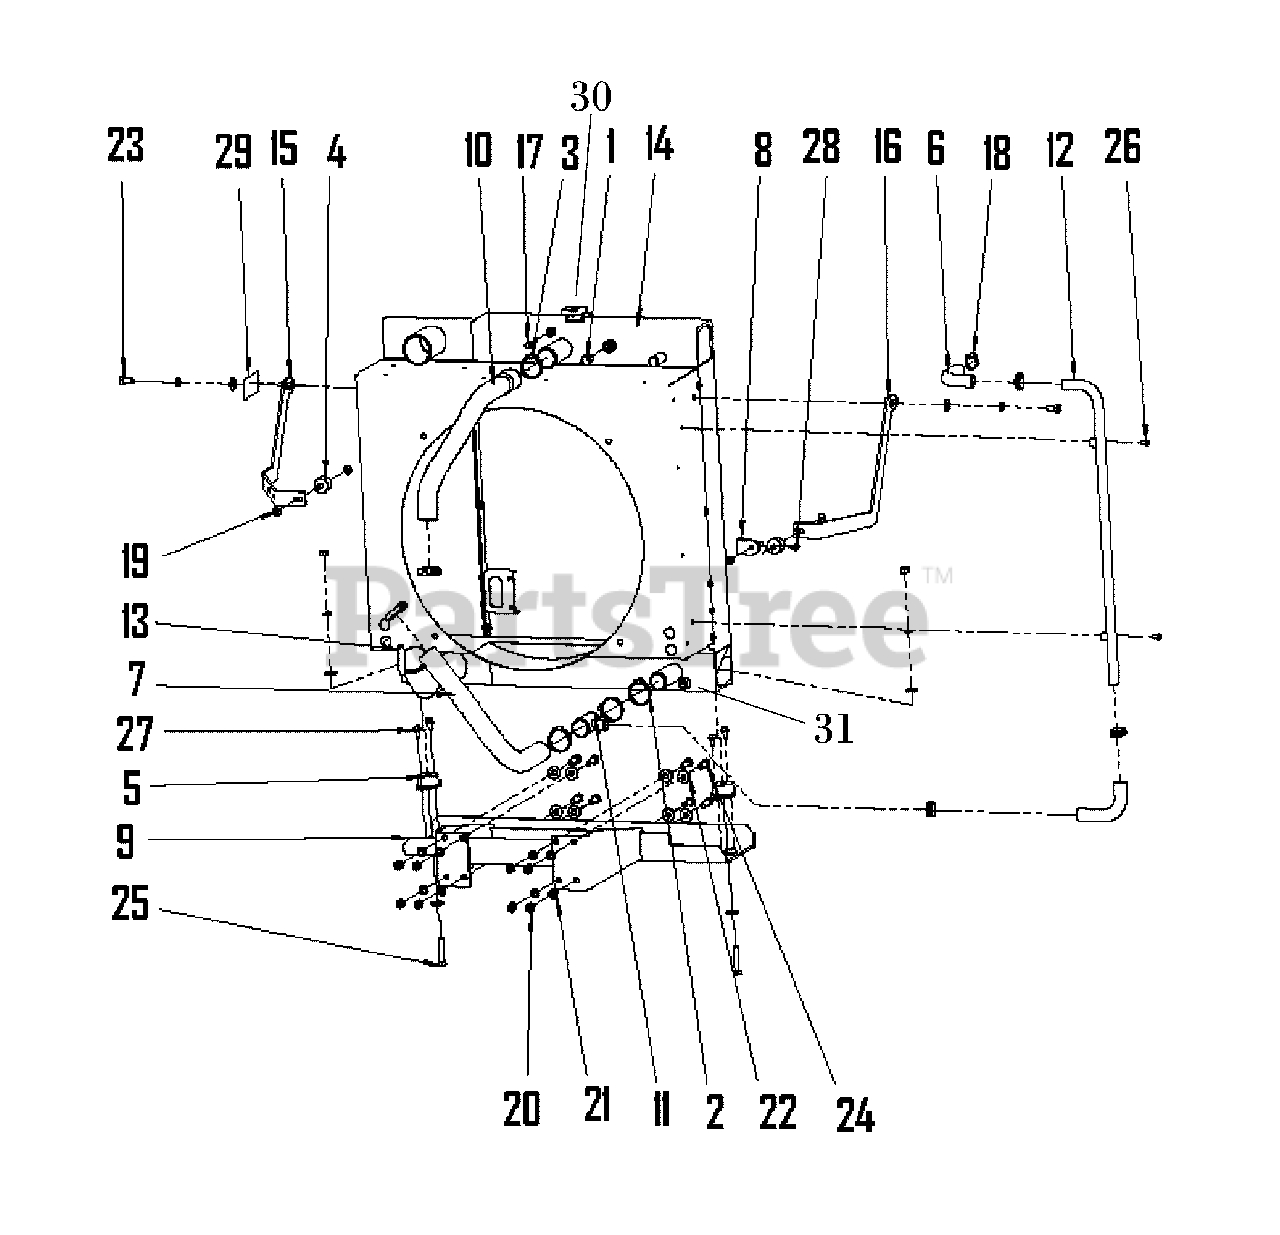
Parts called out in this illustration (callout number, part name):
1	* PLUG
3	* CLAMP
4	* ISOLATOR
5	* ISOLATOR
6	* HOSE
8	* BRACKET
9	* SUPPORT
11	* PIPE
12	* PIPE
13	* TRIM
15	* BRACKET
16	* BRACKET
17	* PLUG
18	* CLAMP
19	* NUT
20	* NUT
21	* WASHER
22	* WASHER
23	* BOLT
24	* BOLT
25	* BOLT
26	* BOLT
27	* BOLT
28	* BOLT
29	* STICKER
